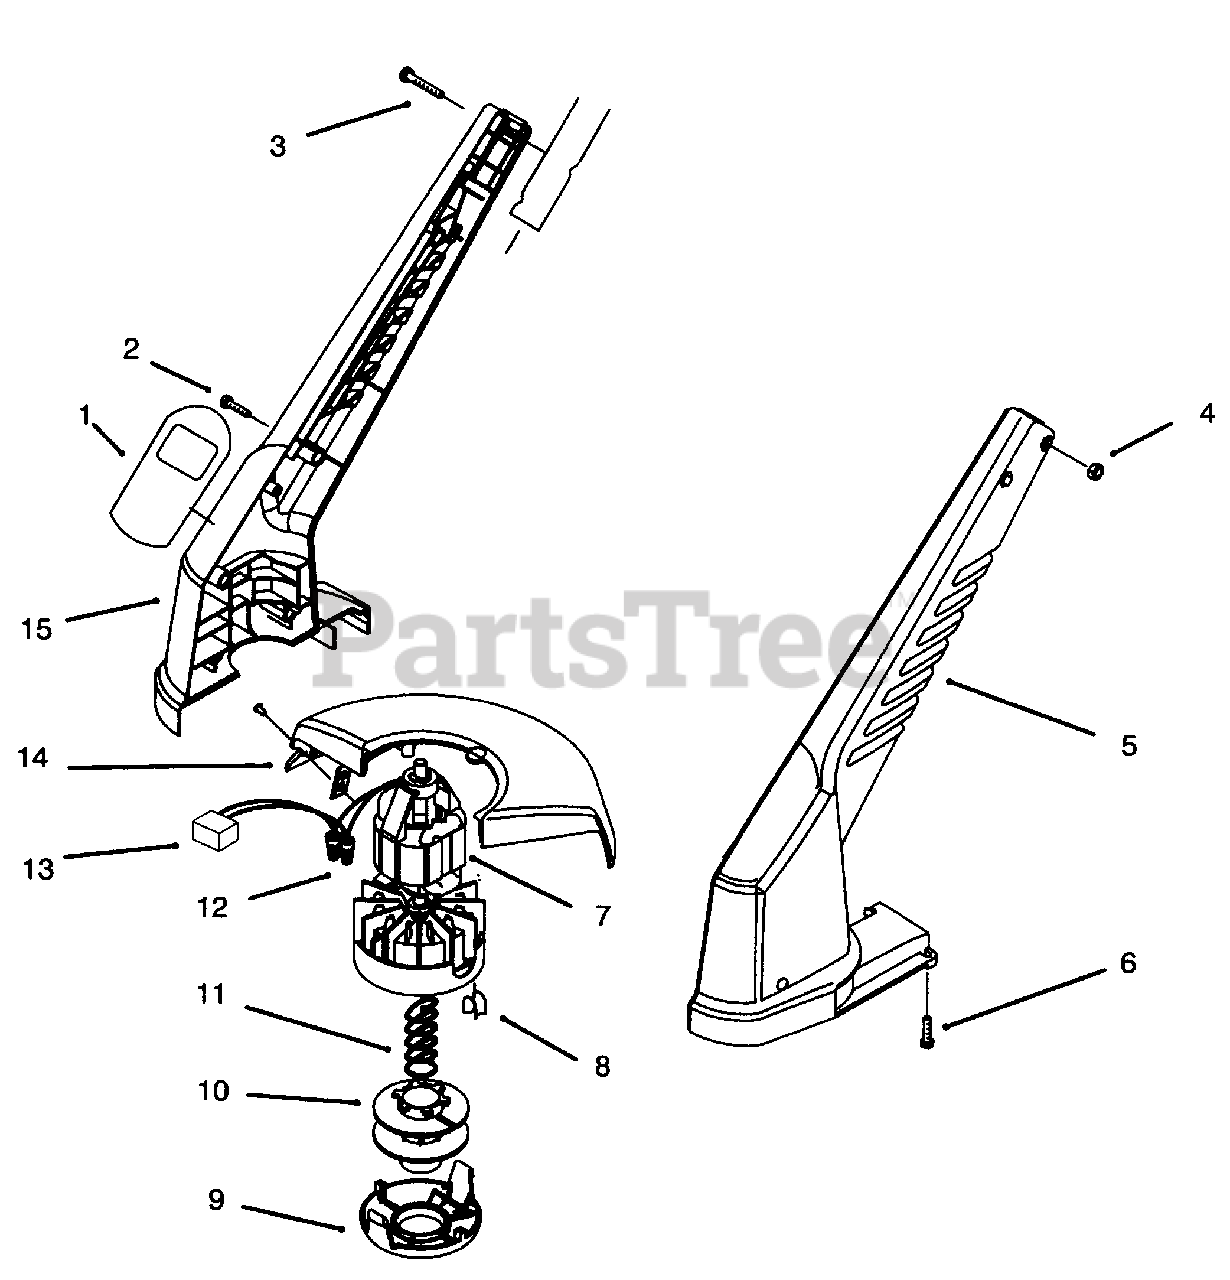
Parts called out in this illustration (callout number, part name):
1	Decal-25CM Trimmer
2	Housing R.H.
3	Screw-Pan Hd.
5	Housing L.H.
6	Screw-Pan Hd. Tapping
7	Motor Assembly-Trimmer (Incl. Ref. #8)
12	Connector-Wire Nut
15	Housing R.H.
